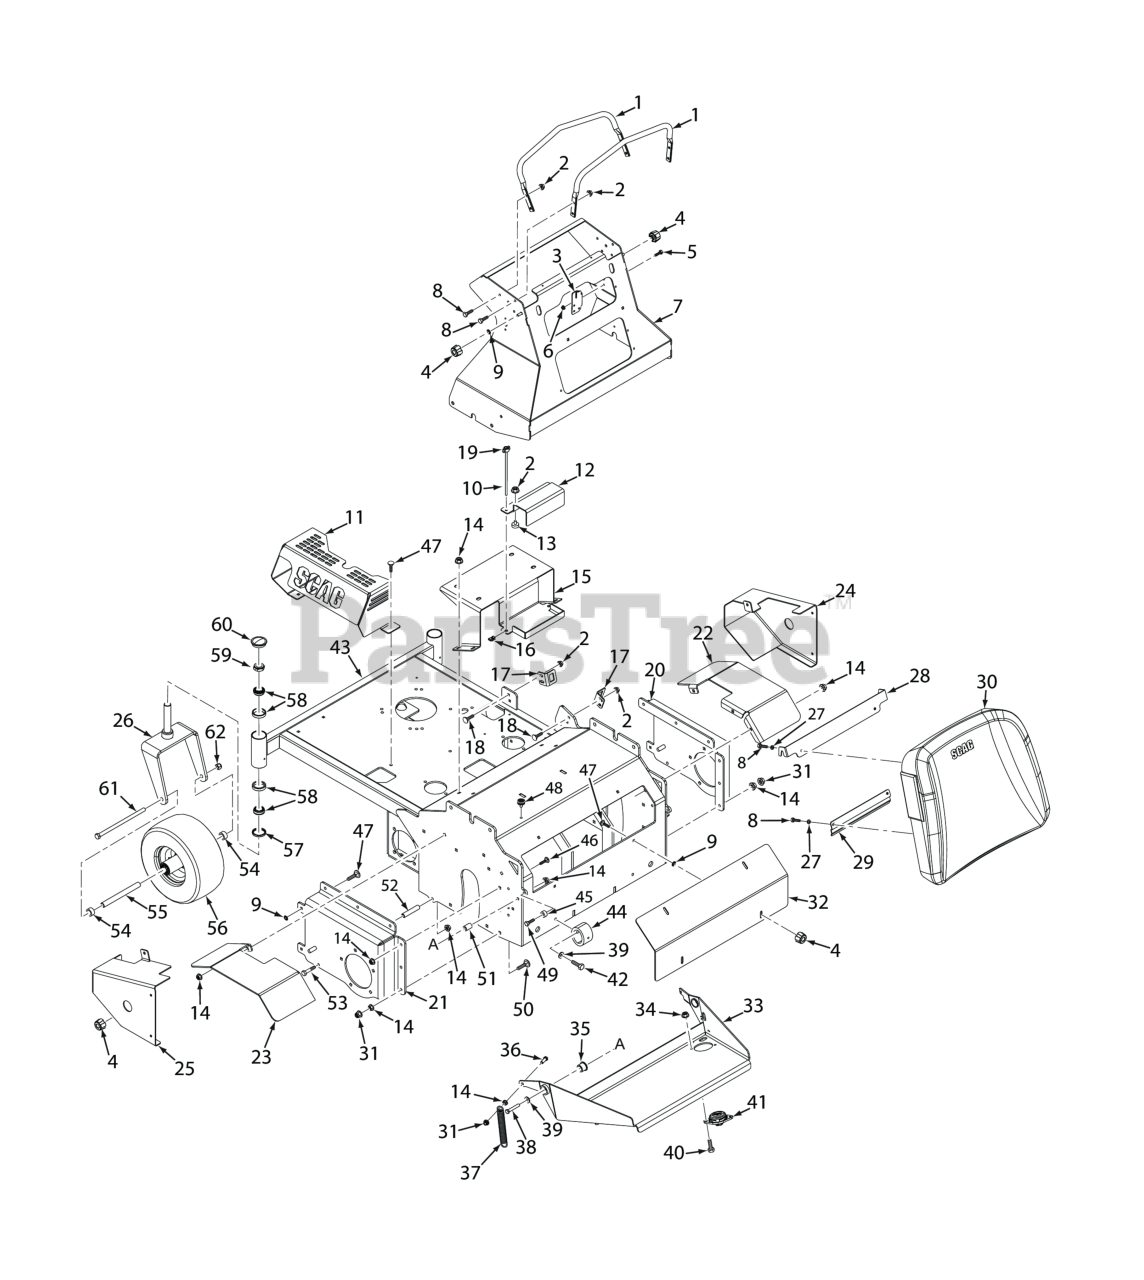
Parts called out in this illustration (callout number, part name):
1	Reference Bar
2	Nut, Serrated Flange 5/16-18 (Right Front Engine Mounting, Briggs and Kohler Only)
3	Bracket, Neutral Switch
4	Knob, 5/16-18
5	BOLT, HEX HEAD, 1/4-20 X 3/4 GR.5
6	NUT, 1/4-20 SERRATED FLANGE HEX HEAD
7	Handlebar Weldment
8	BOLT, SERRATED FLANGE HEX HEAD 5/16-18 X 3/4"
9	Nut, Push-On 5/16-18
10	Bolt, Hex Head 1/4-20 x 8"
11	Heatshield, Muffler
12	Cover, Battery Box
13	Bumper, Rubber 5/16-18 x 5/8"
14	NUT, 3/8-16 SERRATED FLANGE HEX HEAD
15	Mount, Fuel Tank
16	Bolt, Hex Head 3/8-16 x 1"
17	Bracket, Height Switch
18	Bolt, 5/16-18 x .75 RHSN Carriage
19	Knob, 1/4" Wing
20	Bracket RH, Wheel Mount
21	Bracket LH, Wheel Mount
22	Fender RH
23	Fender LH
24	Chain Cover, RH
25	Chain Cover, LH
26	Yoke Weldment
27	Lockwasher, 5/16 (.317 x .586 x .078) Helical Spring
28	Bracket, Knee Pad - Upper
29	Bracket, Knee Pad - Lower
30	Operator Pad
31	Nut, Flange Elastic Stop Nut, 3/8-16
32	Guard, Rear
33	Footplate
34	Nut, Flange Head Elastic Stop 5/16-18
35	Bearing, Pivot
36	Bolt, Hex Head 3/8-16 x 1-1/4", Kawasaki FX / FT & FT-EFI
37	Spring,Counter Balance
38	Bolt, Hex Head 3/8-16 x 2-1/4" - 61"
39	Flatwasher, 3/8" Special (.391 x .938 x .105)
40	Bolt, Heax Head 5/16-18 x 1" (48V / 52V)
41	Switch, Foot
42	Bolt, Hex Head 3/8-16 x 1-1/2" B&S 32BV
43	Frame
44	Isolator, Footplate
45	Spacer, Idler Pulley - SFZ61
46	Carriage Bolt, 3/8-16 x 1.0"
47	Bolt, 5/16-18 x .75 RHSN Carriage
48	Bumper, Rubber 5/16-18 x 5/8"
49	Bolt, Hex Head, 3/8-16 x 1 Gr. 5
50	Carriage Bolt, 3/8-16 x 2-1/2"
51	Bearing, Hub
52	Spacer, Wheel Mount
53	Bolt, Hex Head 3/8-16 x 4.00
54	Spacer, Caster Wheel
55	Sleeve, Caster Wheel (61V, 72A/VS)
56	REPLACED BY 9278
57	Seal, 2.00" O.D. x 1.625" Bore
58	Bearing, 1.0 Diameter
59	Nut, Elastic Stop 1.0"-14
60	Cap, Grease
61	Bolt, Hex Head 1/2-13 x 9-1/2" (61V & 72A/VS)
62	HEX LOCKNUT, ELASTIC STOP, 1/2-13
